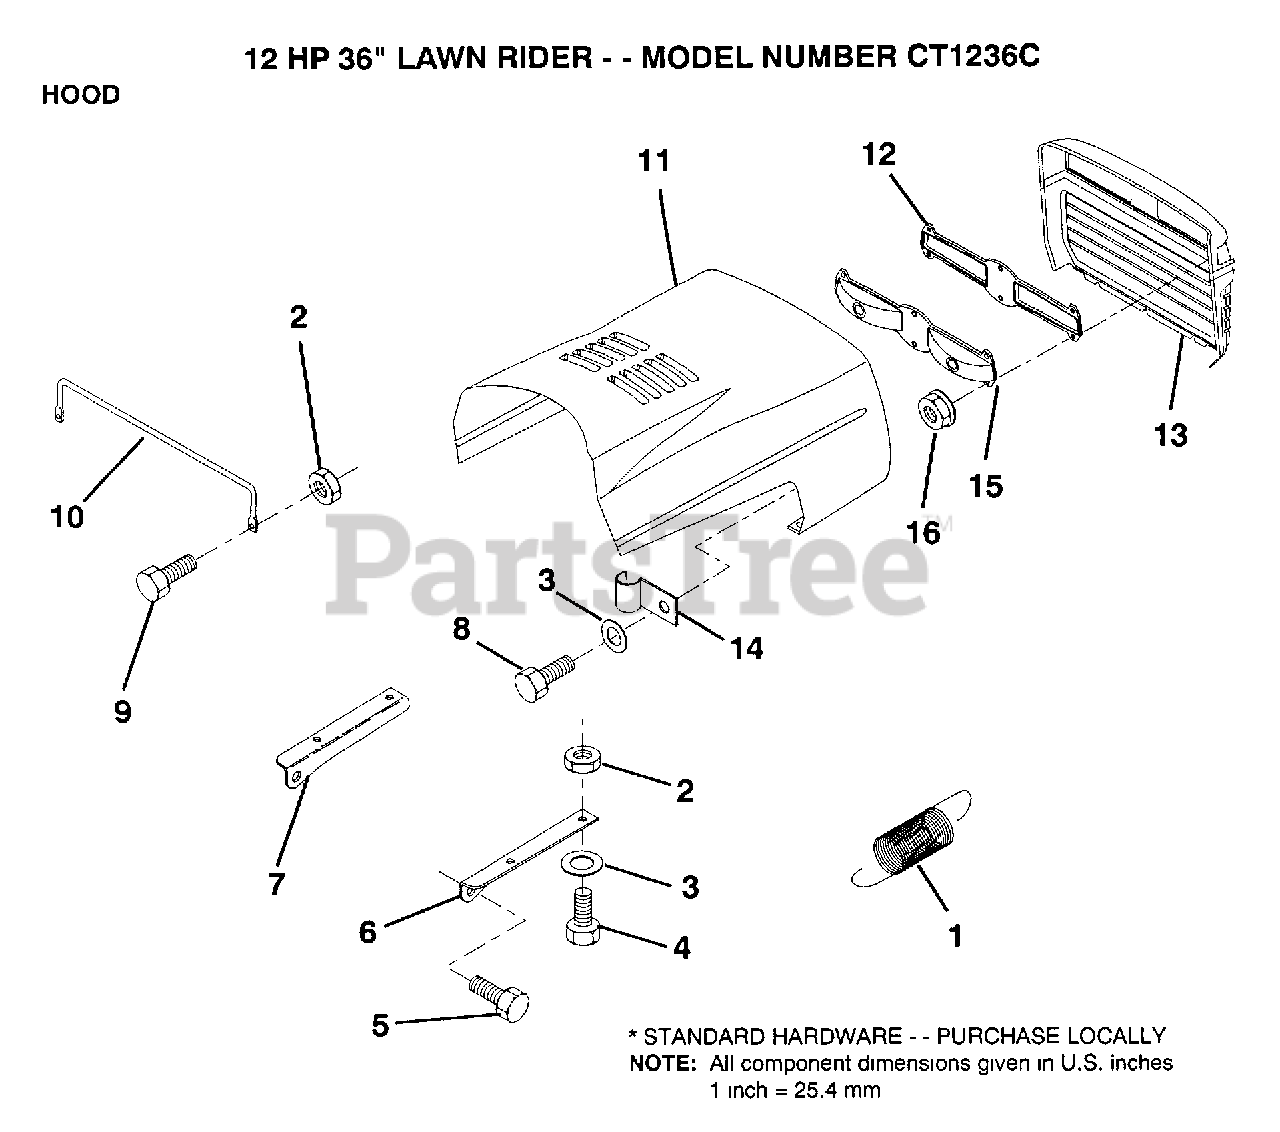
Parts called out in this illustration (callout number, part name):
1	EXT SPRING
2	NUT
3	WASHER
4	BOLT
6	BRKT HOOD RH
7	BRKT HOOD LH
10	"BRACE,HOOD"
14	CLIP T
16	NUT
